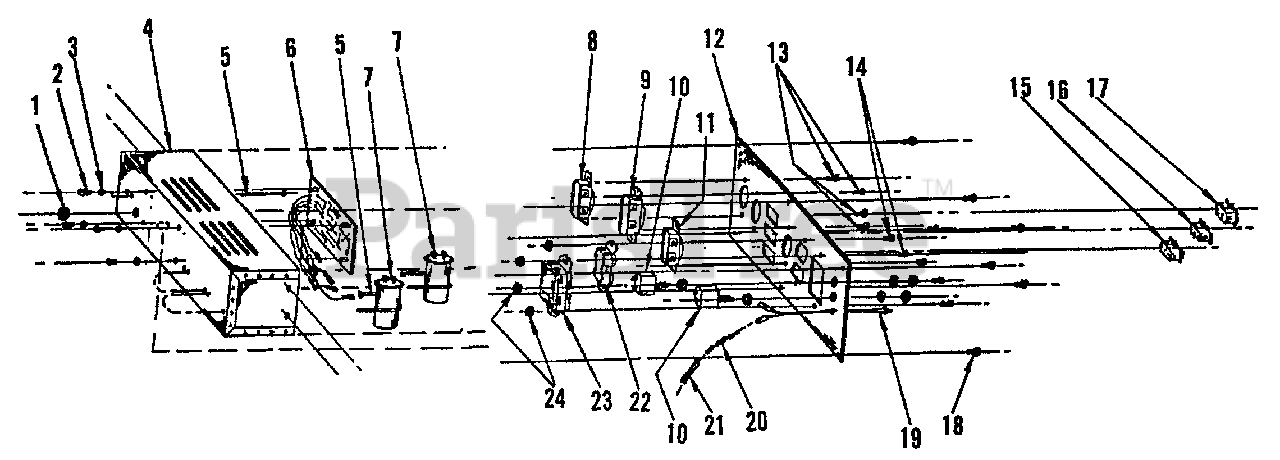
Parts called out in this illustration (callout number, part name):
1	GROMMET
2	6-32X 1/4 RHS
3	LOCKWASHER - 6
4	BOX, CONTROL
5	TIE, CABLE
6	CIRCUIT, ECHO-MIZER
7	CAPACITOR - 50UF 370V
8	LOCK, TWIST - 30A/125V/250V
9	LOCK, TWIST - 30A/250V
10	BREAKER, CIRCUIT - 30A/250V
11	LOCK, TWIST - 30A/125V
12	PANEL SILKSCREEN
13	6-32X3/8 RHS
14	8-32X3/8 RHS
15	SWITCH, ECHO-MISER
16	SWITCH, FULL POWER
17	SWITCH, IGNITION
18	SCREW - 10-24
19	INDICATOR - LOW OIL
20	RESISTOR ASSY
21	SLEEVING, INSULATOR
22	DUPLEX, 15A/125V
23	GFCI - 15A/125V
24	NUT - 8-32 -- KEPS
